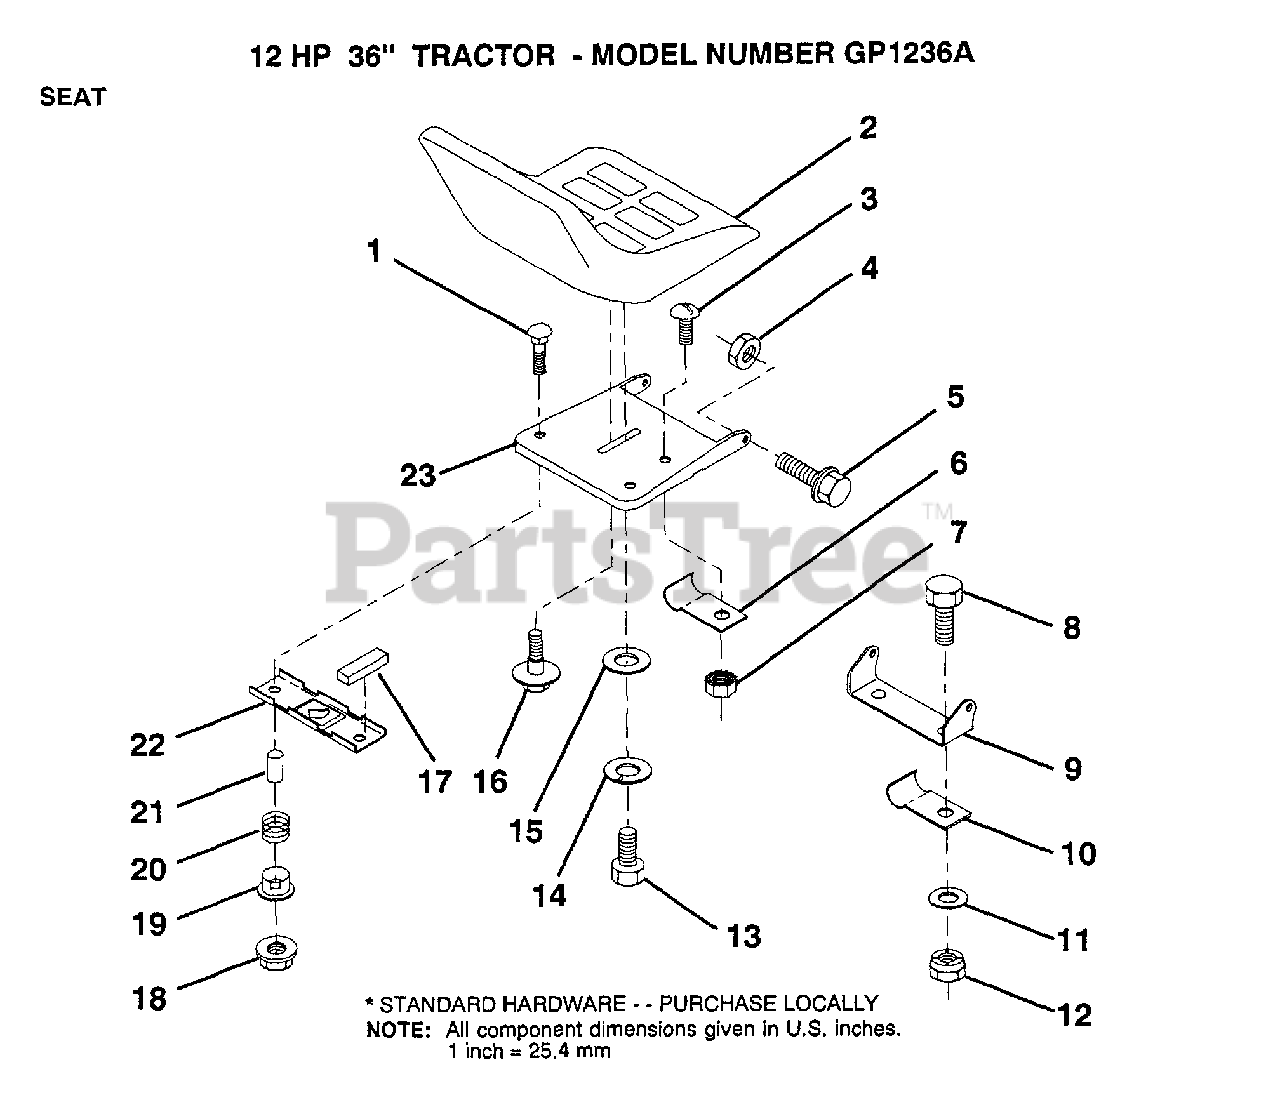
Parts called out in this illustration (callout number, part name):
7	"NUT,KEPS"
10	"CLIP,INSULATOR"
11	WASHER
13	BOLT
14	LOCKWASHER
15	WASHER
16	"BOLT,SHOULDER"
17	STRIP FORM
19	BUSHING
20	SPRING
21	SPACER SPLIT
22	BRKT SWITCH
